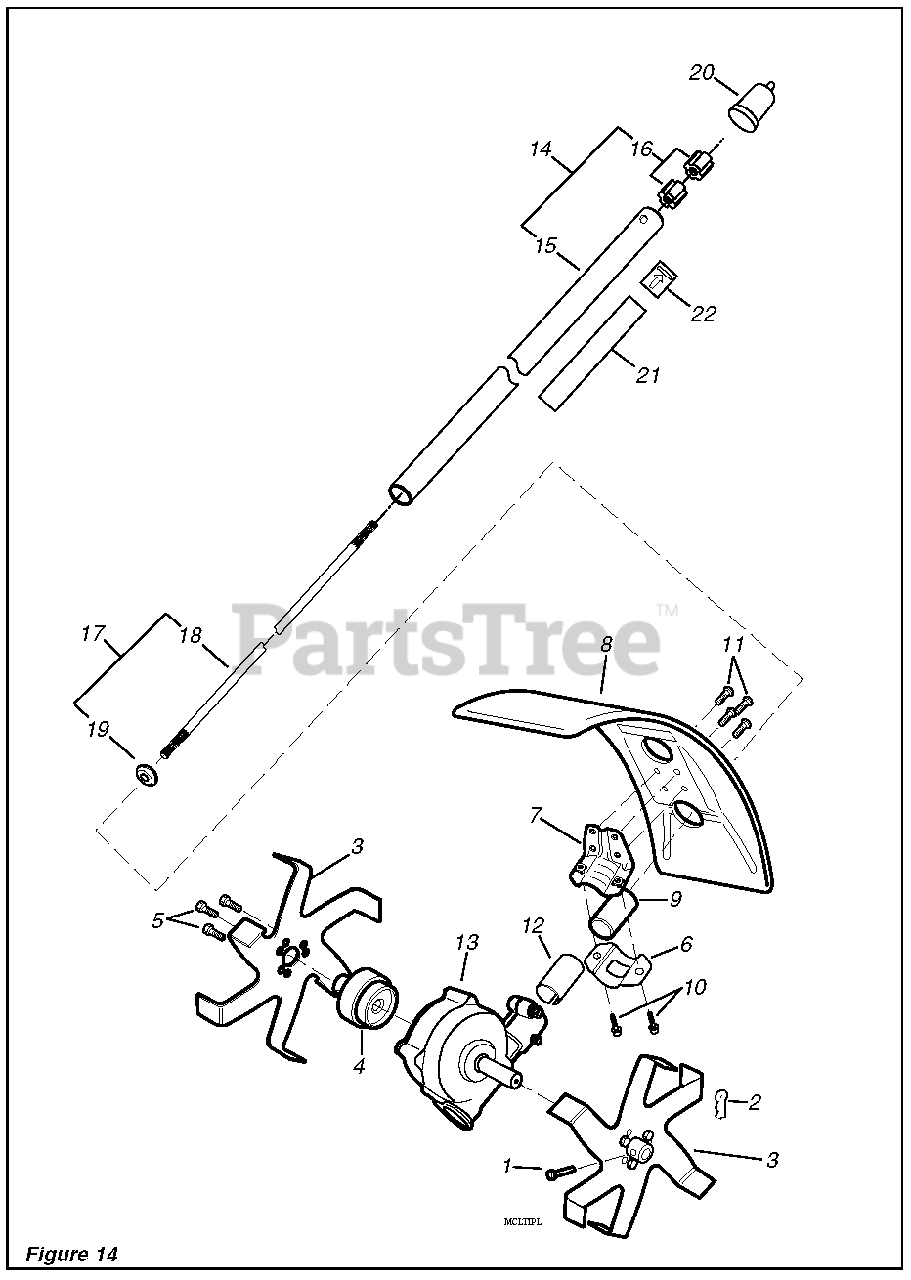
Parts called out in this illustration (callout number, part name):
1	PIN, LOCK
2	PIN, SNAP
3	CUTTER, LINE
4	BRACKET, CUTTER
5	BOLT
6	BRACKET, SHIELD
7	BRACKET, SHIELD
8	SHIELD, DEBRIS
9	COLLAR
10	BOLT
11	BOLT
12	SPACER
13	GEAR CASE
14	MAIN PIPE ASSY
15	PIPE, MAIN
16	BUSHING
17	DRIVESHAFT ASSY
18	MAINSHAFT
19	GROMMET
20	CAP
21	LABEL, CAUTION
22	LABEL, INSTRUCTION
